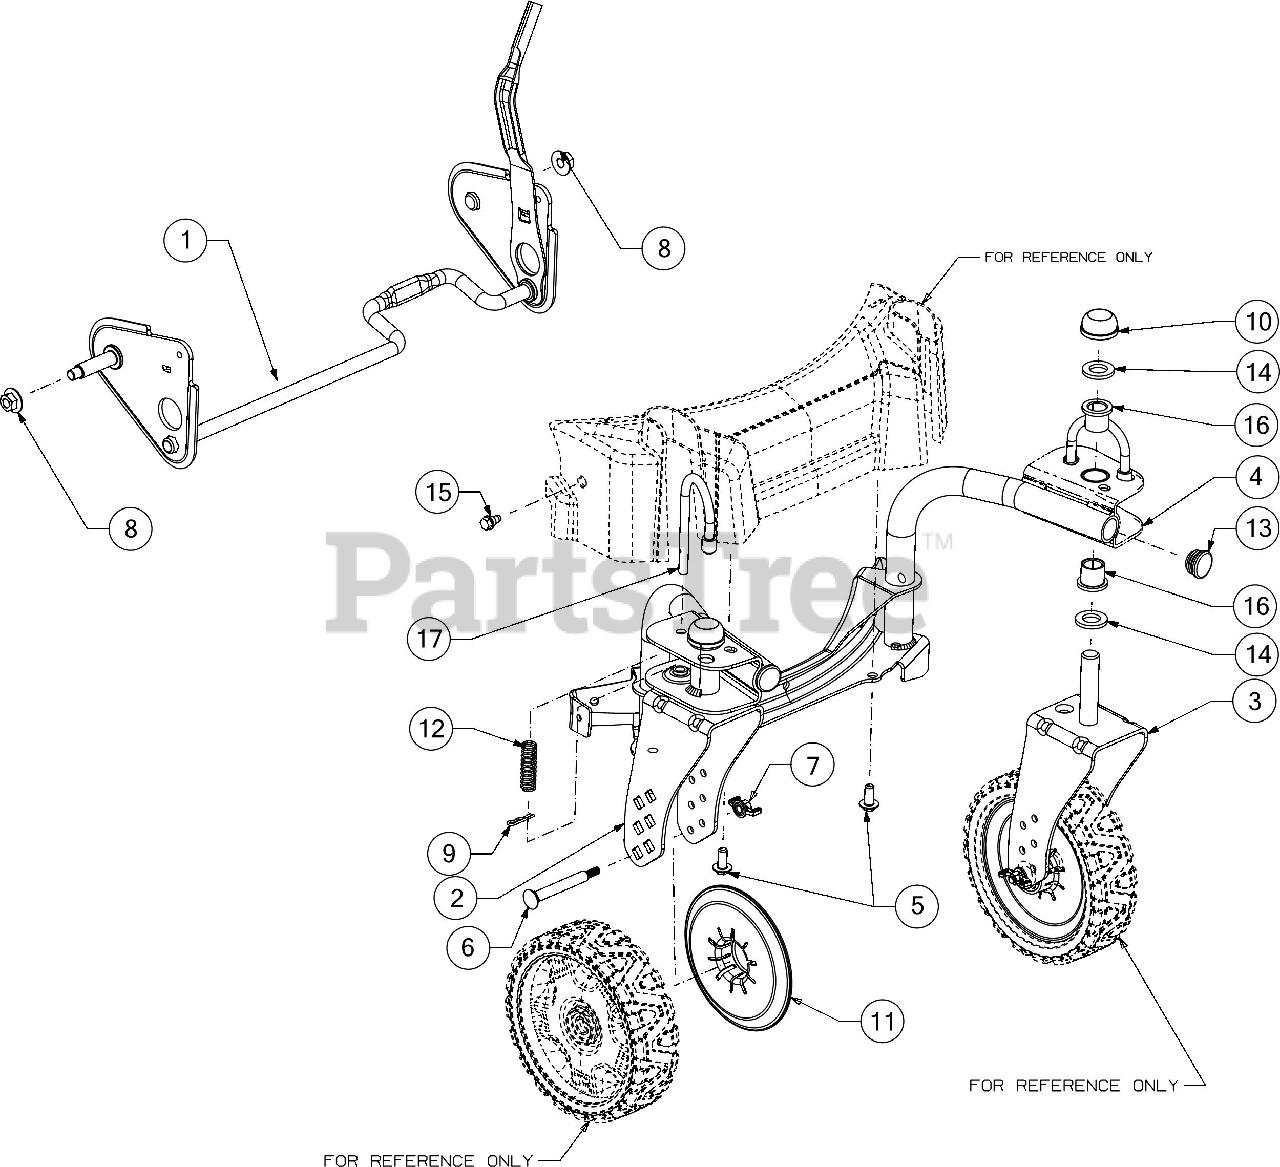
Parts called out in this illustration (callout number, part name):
1	HEIGHT AXLE ASSEMBLY
2	CASTER BRACKET ASSEMBLY (RH)
3	WHEEL BRACKET ASSEMBLY (LH)
4	CASTER BRACKET ASSEMBLY
5	SCREW 5/16-14 x .750
6	CASTER AXLE
8	FLANGE LOCK NUT
9	COTTER PIN .072 DIA
11	DUST COVER 7"
12	COMPRESSION SPRING
14	FLAT WASHER
15	SHOULDER SCREW 1/4-20 x .50
16	BEARING:FLANGE .631 ID
